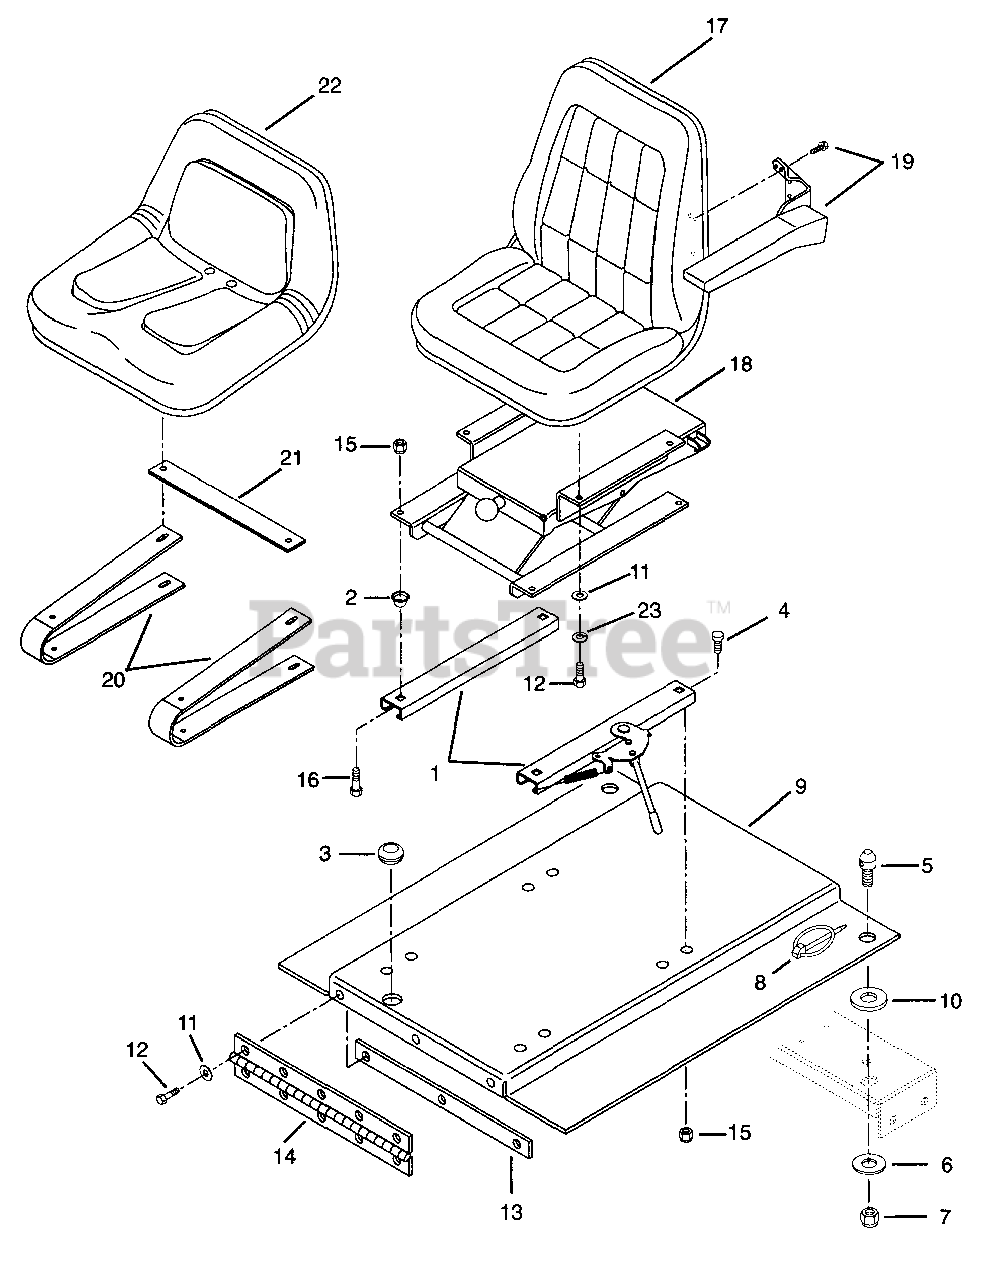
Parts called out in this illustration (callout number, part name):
1	Seat Slides
2	Seat Slide Spacer
3	Grommet .75 x 1.06 x 1.38
4	Screw-Cap Button Head .31-18 x .50 Grade 5
5	Pin, Catch
6	Washer-Flat-Steel .531 x 1.06 x .095
7	Nut-Locking-Nylon .50-13 Grade 5
8	Pin-Klik .25 x 1.75
9	Plate, Deck
10	Washer-Snub-Steel .53 x 2.38 x .125
11	Washer-Flat-Steel .344 x .688 x .065
12	Bolt-Hex .31-18 x .75 Grade 5
13	Plate, Clamping
14	Hinge
15	Nut-Locking-Nylon .31-18
16	Bolt-Hex .31-18 x 1.00 Grade 5
17	Seat, Pro Master
18	Seat, Suspension
19	Kit-Pro Master Arm Rest
20	Spring, Seat
21	Plate, Control Shaft
22	Seat, V-560 High Back
23	Washer-Locking .31 x .078
